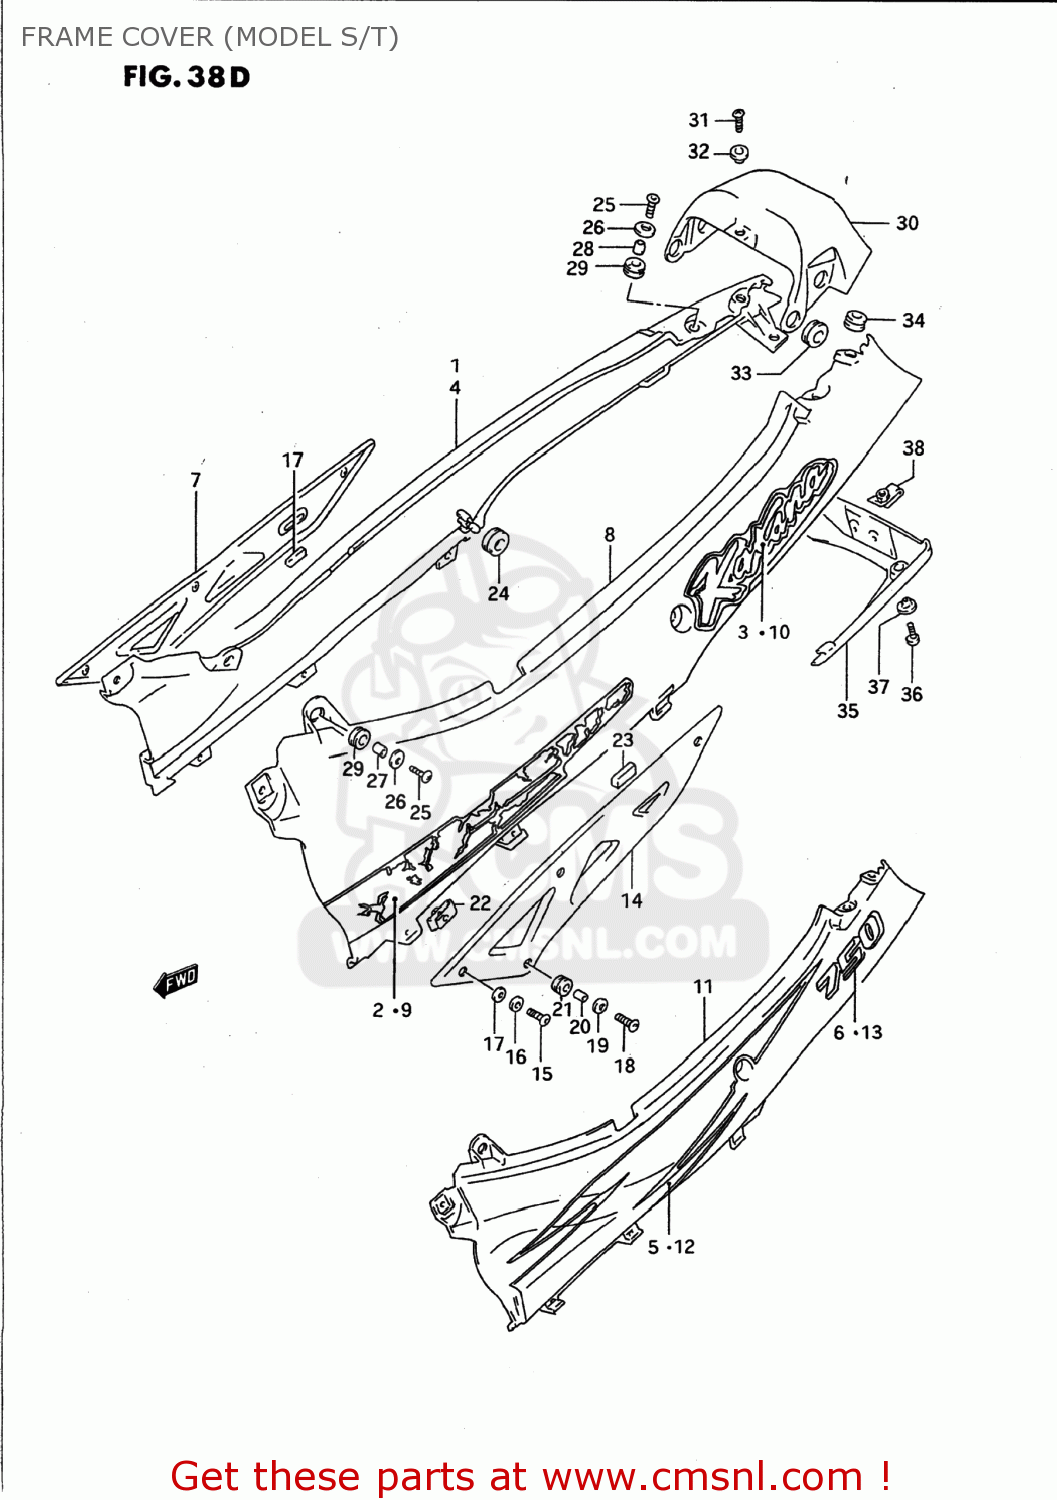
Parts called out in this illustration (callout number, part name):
1	COVER,FRAME,RIGHT
2	TAPE,FRAME COVER,R
3	EMBLEM,FRAME COVER
4	COVER,FRAME,R(GREEN)
5	TAPE,FRAME COVER,R
6	EMBLEM,FRAME COVER
7	COVER,FRAME LWR,R
8	COVER,FRAME,LEFT
9	TAPE,FRAME COVER,LEFT
10	EMBLEM,FRAME COVER
11	COVER,FRAME,L(BLACK)
12	TAPE,FRAME COVER,LEFT
13	EMBLEM,FRAME COVER
14	COVER,FRAME LWR,L
15	SCREW(6X16)
16	WASHER (6.7X16X1.8)
17	WASHER (5.5X16X1)
18	SCREW(6X16)
19	WASHER(6.5X22X1.6)
20	SPACER(6.2X8.3X6.1)
21	CUSHION
22	PLATE,FRAME COVER
23	CUSHION,FRAME COVER LWR
24	CUSHION
25	SCREW(6X16)
26	WASHER
27	SPACER(6.1X9X7.5)
28	SPACER (6.1X9X9)
29	CUSHION
30	COVER,FRAME CTR
31	SCREW 6X10
32	WASHER
33	GROMMET
34	CUSHION
35	COVER,FRAME RR
36	SCREW
37	WASHER
38	PLATE,FRAME COVER
